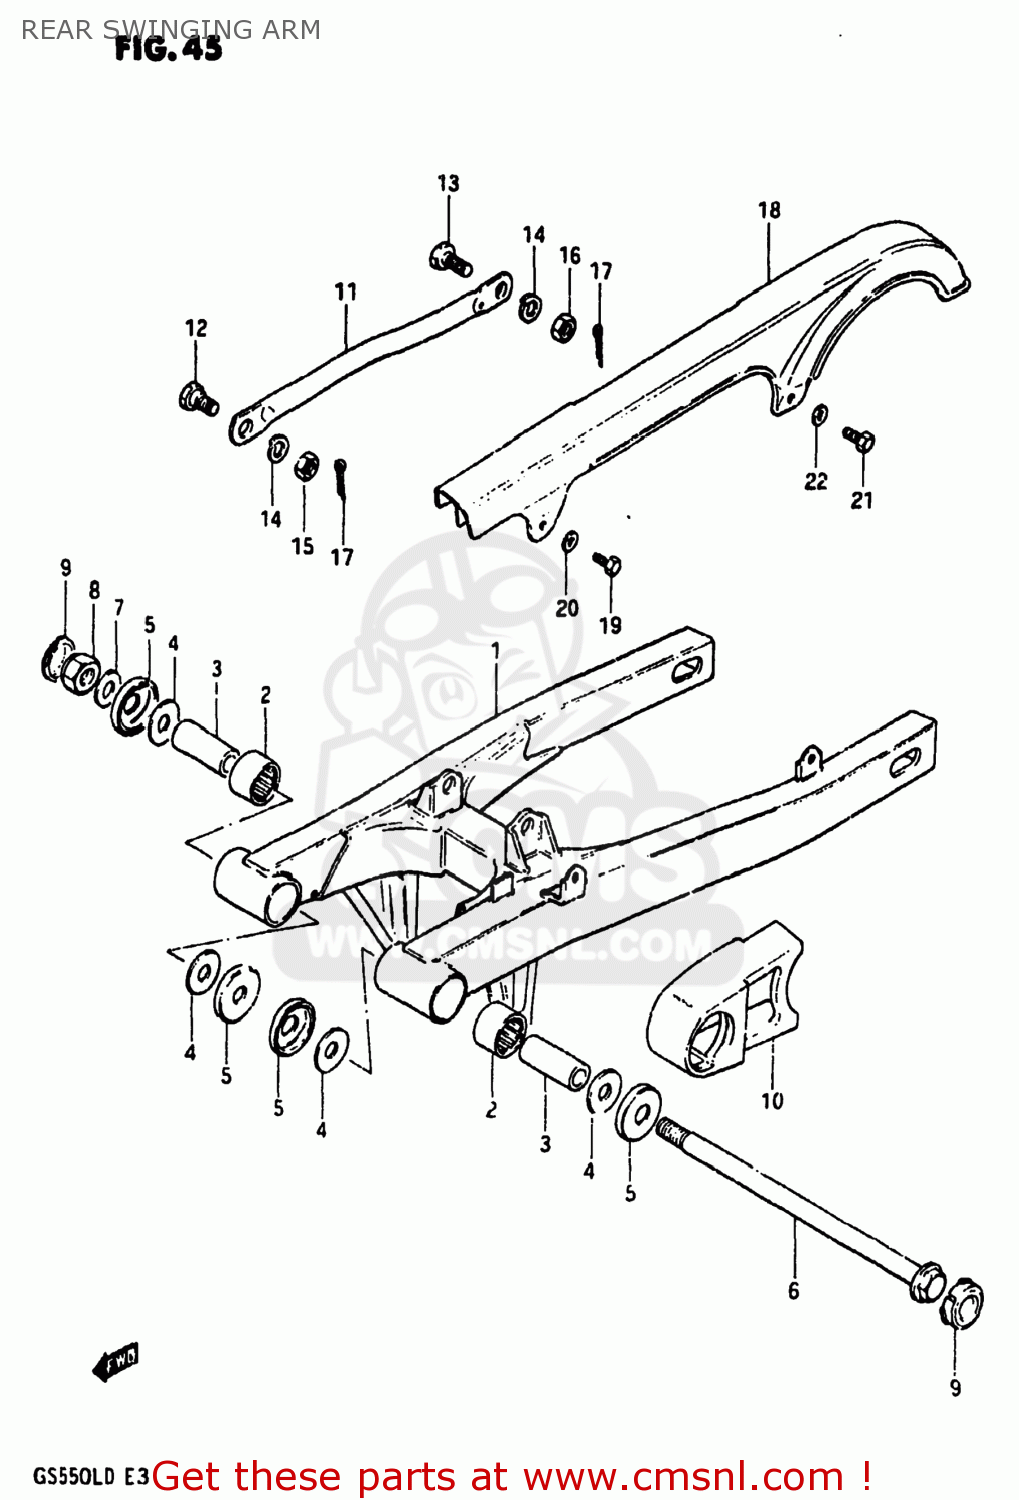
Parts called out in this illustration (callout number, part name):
1	ARM,REAR SWING
2	BEARING(25X33X30)
3	SPACER,REAR SWING ARM PIVOT
4	WASHER
5	COVER,RR SWGARM DUST SEAL
6	SHAFT,REAR SWING ARM PIVOT
7	WASHER
8	NUT 14MM
9	CAP,SWINGINGARM PIVOT
10	BUFFER,CHAIN TOUCH DEFLECTOR
11	TORQUE LINK,REAR
12	BOLT(10X24.5)
13	BOLT(10X31)
14	LOCK WASHER
15	NUT
16	NUT
17	PIN 20X20
18	CASE,CHAIN
19	BOLT
20	WASHER
21	BOLT, UPPER
22	WASHER
